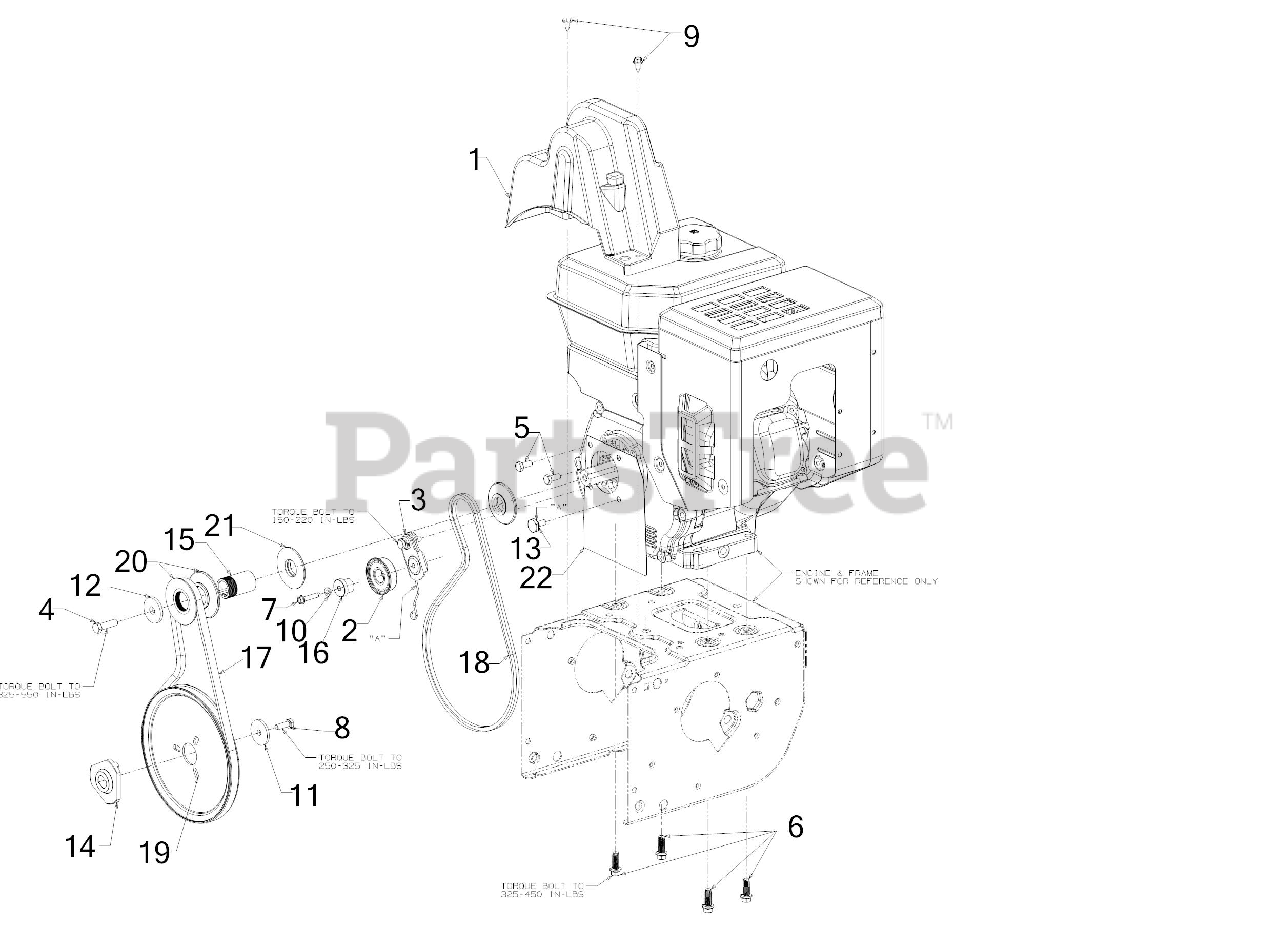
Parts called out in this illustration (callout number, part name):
1	BELT COVER (LARGE BLOCK)
2	IDLER PULLEY ASSEMBLY
3	IDLER BRACKET
4	SCREW 3/8-24X1.25
5	SCREW 5/16-24 x .750 GR5
6	SCREW 3/8-16 x 1
7	SCREW 1/4-20 x 1.25
8	SCREW 5/16-24 x .875 GR5
9	SCREW 1/4-20X.625
10	LOCK WASHER
11	FLAT WASHER
12	FLAT WASHER .45 x 1.5 x .172 HT
13	SHOULDER SCREW
14	ADAPTER PULLEY .75 DIA W/DD
15	PULLEY SPACER
16	SHOULDER SPACER
17	BELT-.500 x 37
18	BELT-3L x 36.64
19	AUGER PULLEY
20	HALF PULLEY 4L V x 2.6 OD
21	HALF PULLEY 3/8-V x 2.2
22	ENGINE PLATE (FRONT COVER)
